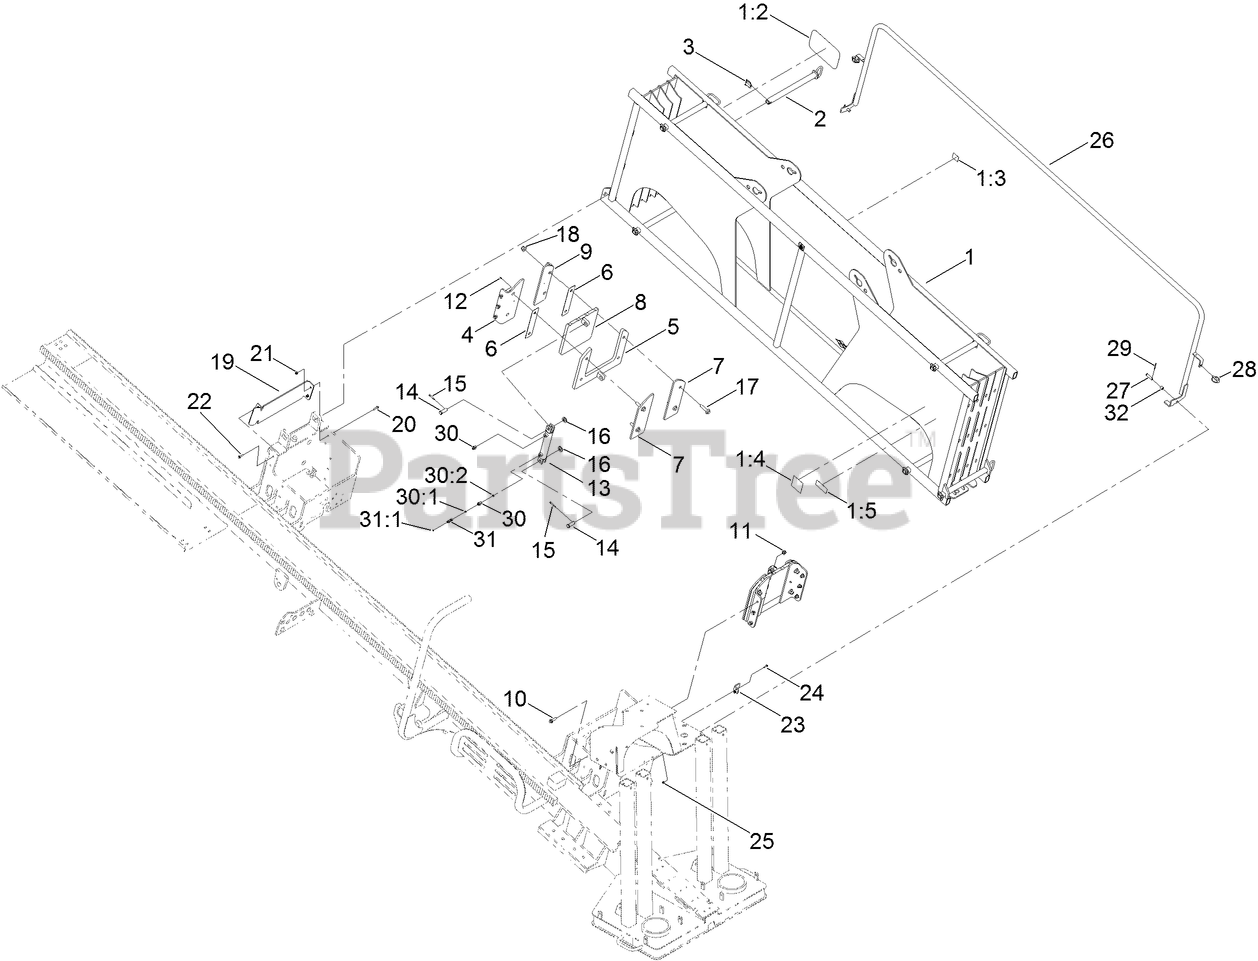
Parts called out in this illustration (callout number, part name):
1	ROD BOX ASM
1:3	DECAL-WEIGHT, ROD BASKET
1:4	DECAL-WARNING, CRUSHING
1:5	DECAL-DANGER, ENTANGLEMENT
2	PIN-ROD BOX
3	PIN-KLIK
4	PLATE-MOUNTING, ELEVATOR
5	PLATE-ELEVATOR
6	PLATE-SHIM, ELEVATOR
7	PLATE-SUPPORT, ELEVATOR
8	MOUNT-CYLINDER, ELEVATOR
9	PLATE-MOUNTING, ELEVATOR
10	SCREW-HHF
11	NUT-HHF, LOCK
12	FITTING-GREASE
13	HYD CYLINDER ASM
14	PIN-CLEVIS
15	PIN-COTTER
16	WASHER-FLAT
17	SCREW-HHF
18	NUT-HHF
19	DEFLECTOR
20	SCREW-HHF
21	NUT-LOCK, HHF
22	SCREW-HHF
23	BRACKET-ANGLE, ROD LDR GUARD
24	SCREW-HHF
25	NUT-FLANGE, NI
27	PIN-CLEVIS
28	PIN-LYNCH
29	PIN-COTTER
30	FITTING-STRAIGHT
30:1	O-RING
30:2	O-RING
31	FITTING-STRAIGHT
31:1	O-RING
32	SPACER-TUBULAR
